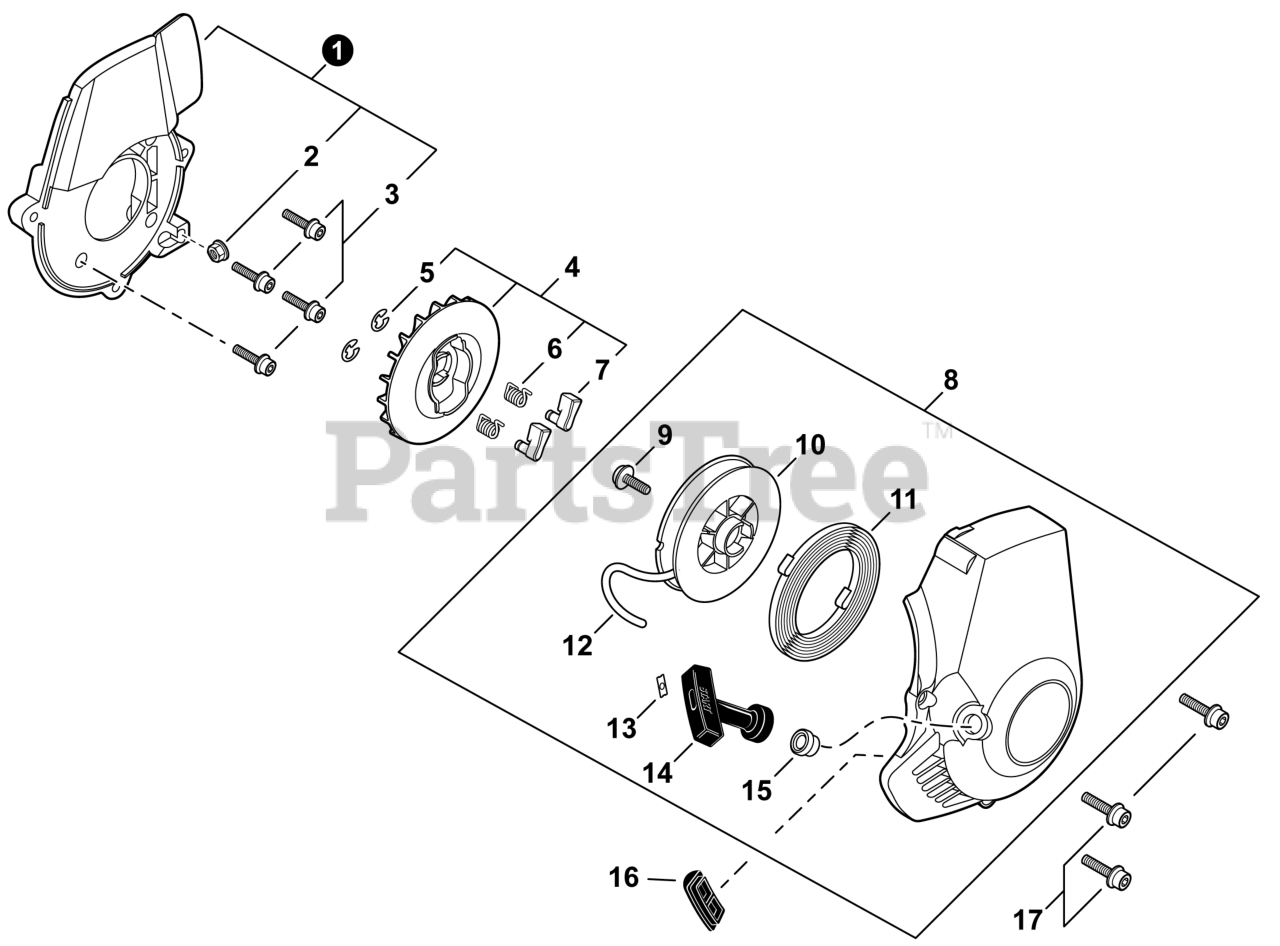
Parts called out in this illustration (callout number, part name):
1	SPACER ASSY.
2	NUT, FLANGE M5
3	BOLT 4x16
4	PAWL ASSY, STARTER
5	E-RING 4
6	SPRING, RETURN
7	PAWL, STARTER
8	STARTER, RECOIL
9	SCREW
10	REEL, ROPE
11	SPRING, RECOIL
12	ROPE, STARTER 3x700
13	RETAINER, ROPE
14	GRIP, STARTER
15	GUIDE, ROPE
16	CUSHION
17	BOLT 5x14
